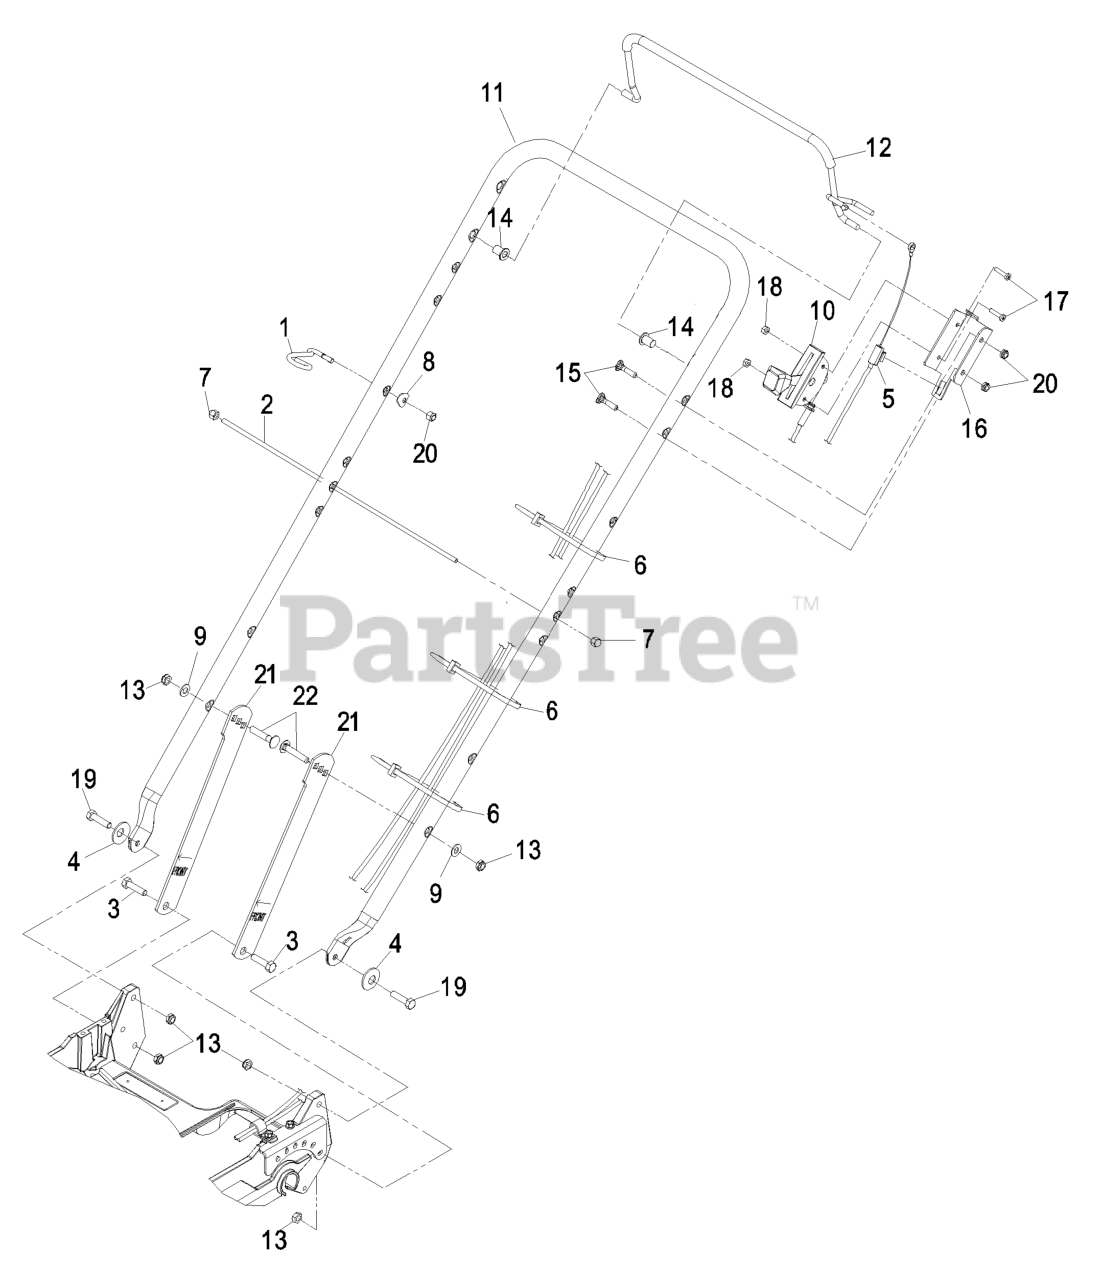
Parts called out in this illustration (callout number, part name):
1	GUIDE-ROPE
2	ROD, BAG SUPPORT
3	SCREW-HH
4	WASHER-BELLEVILLE
5	CABLE,BRAKE KAWASAKI
6	TIE-CABLE
7	NUT-CAP
8	WASHER
9	WASHER-PLAIN
10	CABLE,THROTTLE KAWASAKI
11	HANDLE M21
13	NUT-LOCK, NI
14	BUSHING
15	BOLT-HANDLE
16	BRACKET, THROTTLE
17	SCREW-PPH
18	NUT-LOCK, NI
19	SCREW-HH
20	NUT-LOCK, NI
21	LATCH,HANDLE
22	BOLT-CARR
